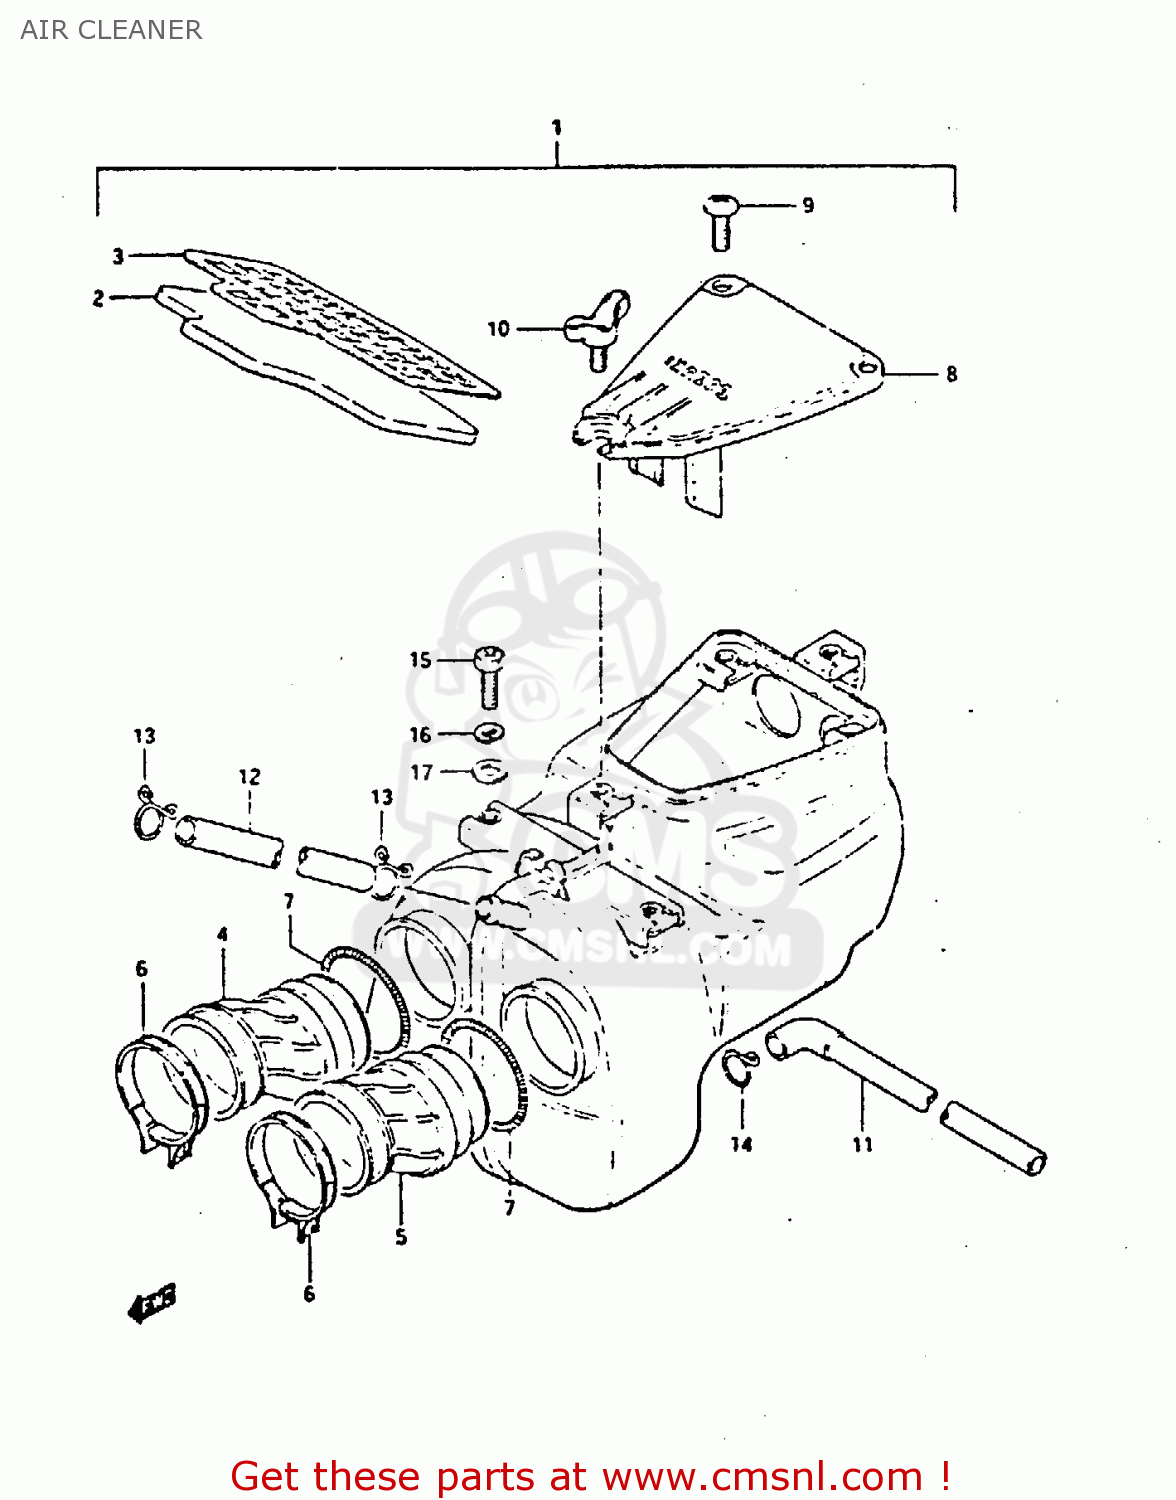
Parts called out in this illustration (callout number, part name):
1	CLEANER ASSEMBLY,AIR
2	FILTER
3	HOLDER,OUTER
4	TUBE,OUTLET,R
5	TUBE,OUTLET,L
6	CLAMP
7	CLAMP,CLEANER SIDE
8	CAP,AIR CLEANER
9	SCREW
10	BOLT, WING
11	DRAIN TUBE
12	TUBE,BREATHER
13	CLAMP
14	CLIP
15	SCREW(6X12)
16	WASHER,LOCK
17	WASHER
